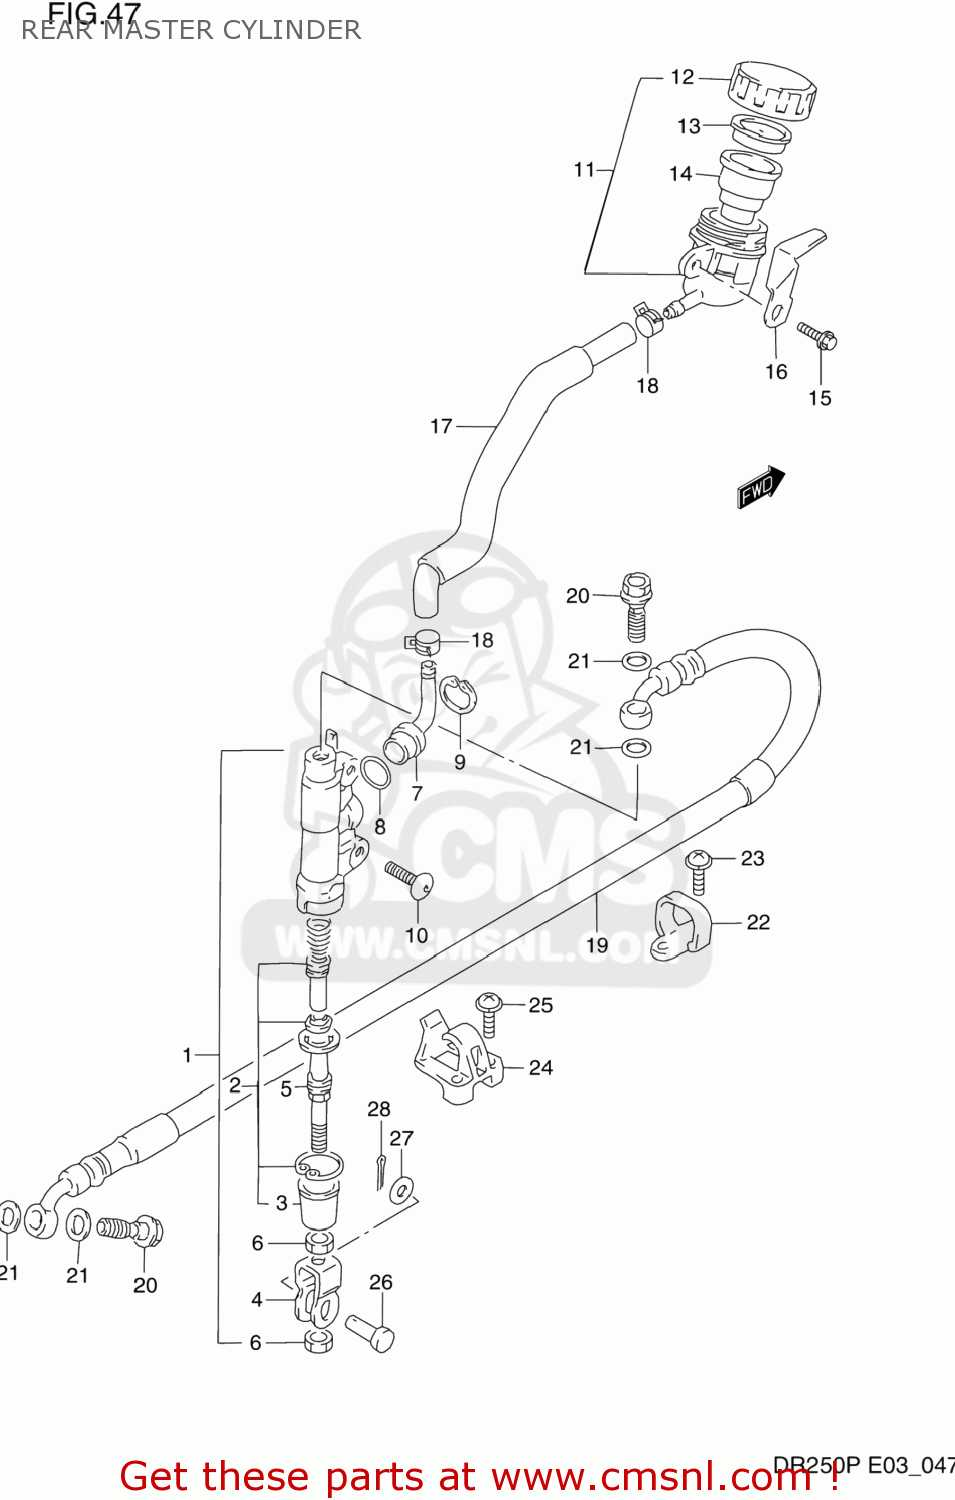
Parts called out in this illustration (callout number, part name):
1	CYLINDER ASSEMBLY,REAR MASTER
2	PISTON/CUP SET
3	BOOT
4	YOKE
5	ROD,PUSH
6	NUT
7	CONNECTOR
8	O RING
9	CIRCLIP
10	SCREW
11	TANK ASSY,RR BRAKE RESERVOIR
12	CAP
13	PLATE
14	DIAPHRAGM
15	BOLT
16	GUARD,RSVR TANK CAP
17	HOSE COMP,RESERVOIR TANK
18	CLAMP
19	HOSE,RR BRAKE
20	BOLT UNION
21	WASHER(10X15X1.5)
22	GUIDE,RR BRAKE HOSE
23	SCREW(5X10)
24	GUIDE,RR BRAKE HOSE
25	SCREW
26	PIN(8X20)
27	WASHER(8.5X13X1.6)
28	PIN 20X15
